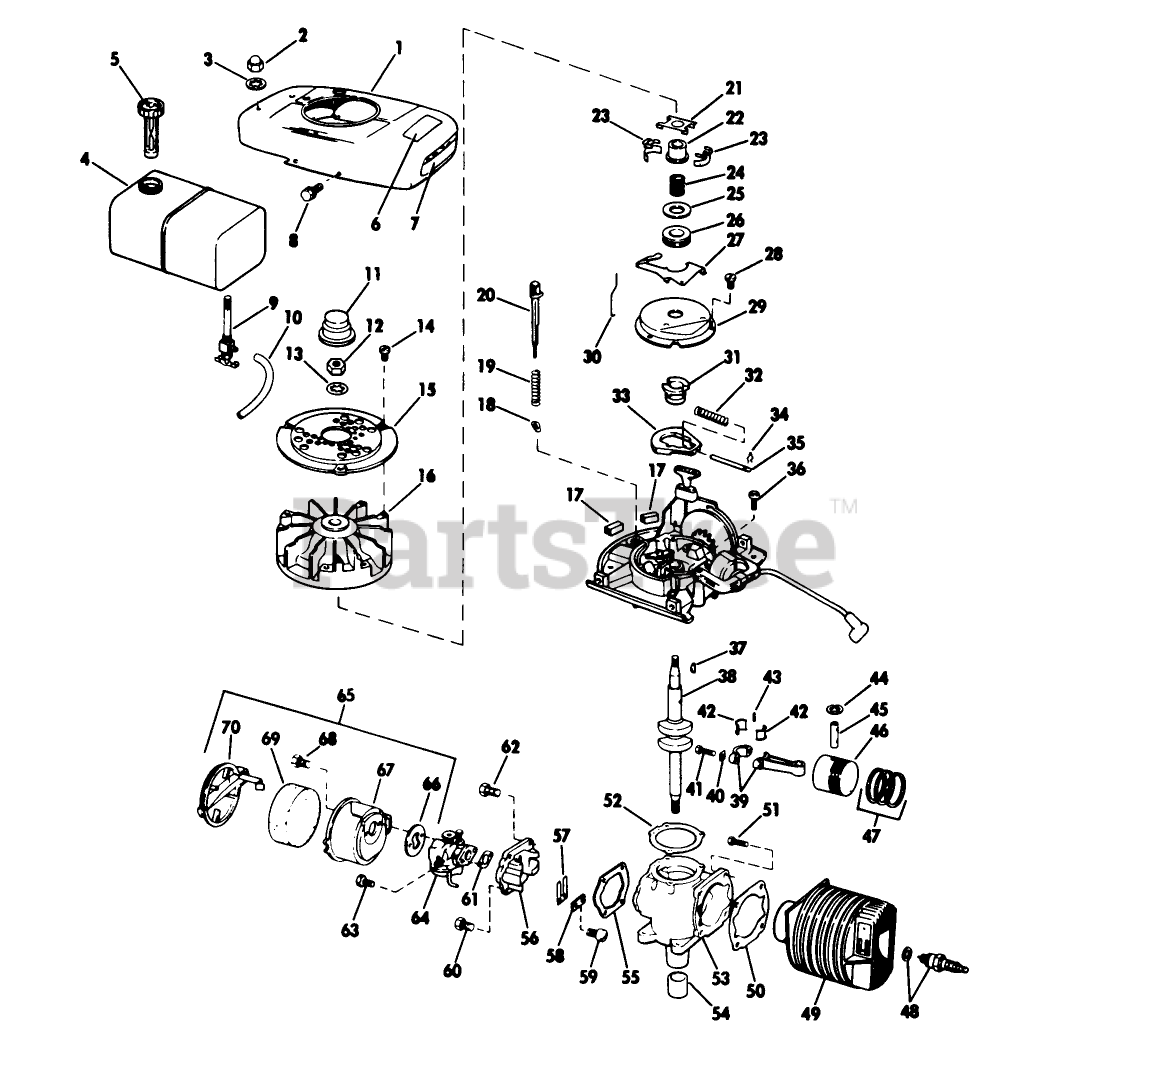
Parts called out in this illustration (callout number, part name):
2	PALNUT S
9	VALVE&SCREEN SM
19	SPRING S
22	COLLAR S
26	THRUST COLLAR S
27	LEVER-GOVERNOR S
28	SCREW S
29	DUST COVER S
31	SPARK ADV. S
32	SPARK ADV. SPRING S
33	FLYWEIGHT S
34	SPARK ADJ. SPRING
35	PIN,SPARK ADV. S
42	LINER ASM
44	RING-RETAINING
50	GASKET S
52	GASKET S
58	PLATE-BACKUP, REED
60	SCREW S
61	GASKET S
62	SCREW S
68	SCREW S
69	AIR FIL.ELEM S
